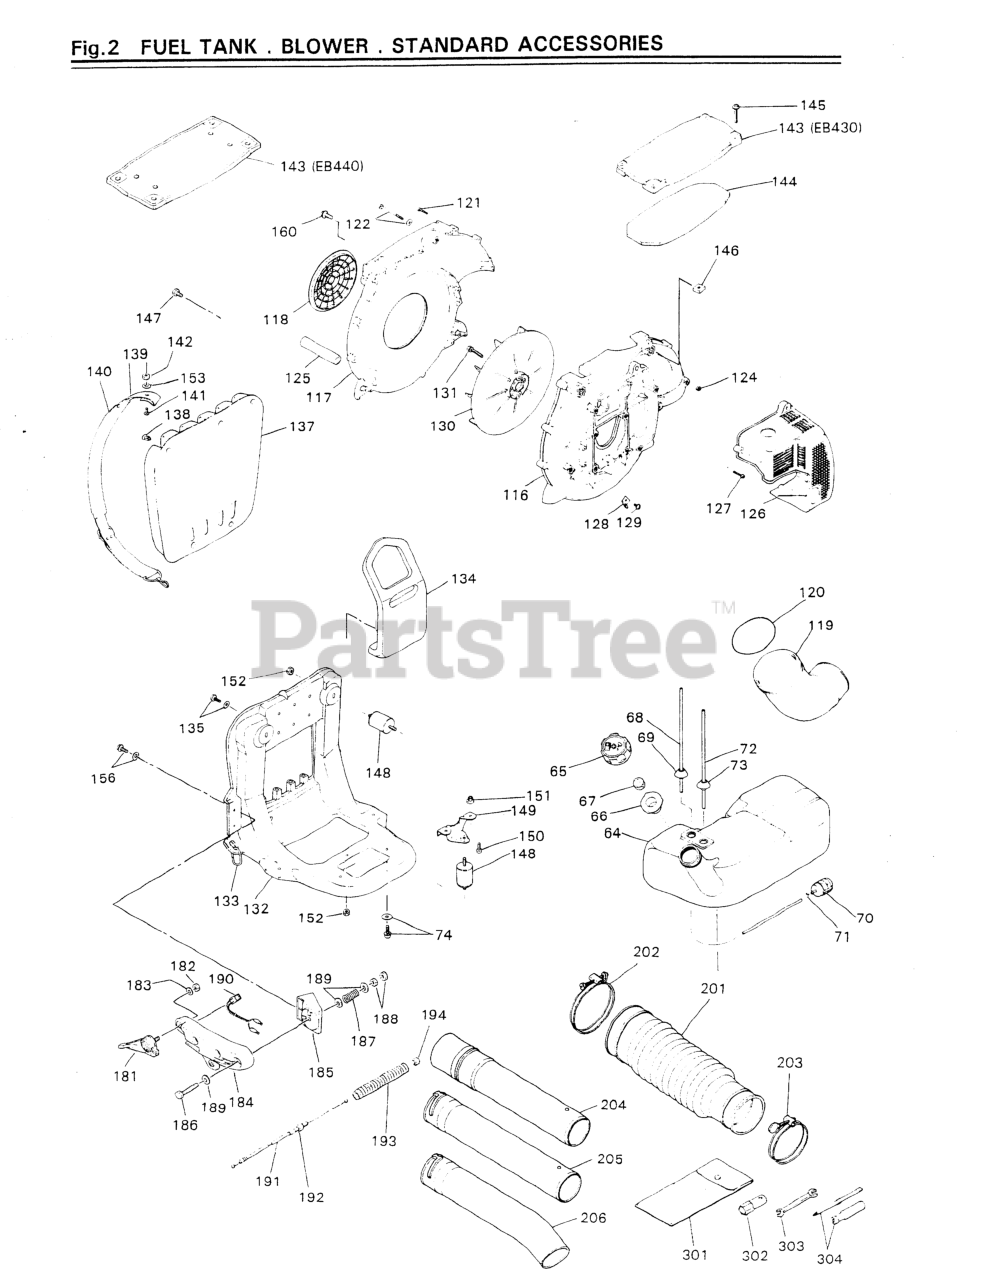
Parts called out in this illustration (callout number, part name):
65	CAP ASSEMBLY (USE 3490-23203)
69	GROMMET
71	CLIP (REPLACES 2841-31280)
72	PIPE (USE 1620-81710)
73	GROMMET
120	O-RING
121	SCREW
127	SCREW, M5 x 25
129	SCREW, M5 x 12
130	FAN (USE 3405-12102)
131	BOLT, M6x35 (RPLS -50635)
133	RING (USE -21121)
137	PAD (RPLS -21310)
138	CLIP (RPLS 3490-21320)
139	BAND
141	(NO LONGER AVAILABLE)
142	NUT, M6 X 5
144	COVER, PACKING
145	SCREW
146	NUT
147	BOLT, M5 X 12
150	SCREW, M5 x 16
151	WASHER
152	NUT, M6 X 5
156	BOLT
160	SCREW, M5 X 10
181	LEVER, THROTTLE
182	NUT, M5 X 4
183	WASHER, M5x.8(RPLS 01624-20508
185	BRACKET
186	BOLT, M8 X 50
187	SPRING
189	WASHER, PLANE(USE 01640-20816)
190	SWITCH, STOP
191	CABLE COMP,THROTTLE EB441
192	NUT, M6 X 5
193	TUBE (USE 5548-73310)
194	NUT, M6 X 5
201	HOSE, FLEXIBLE
202	2756-51510 (RPLS. 07280-09832)
204	JOINT, SWIVEL
205	PIPE, EXTENSION
206	PIPE, BENT
304	SCREWDRIVER
NI	PIPE ASSEMBLY
